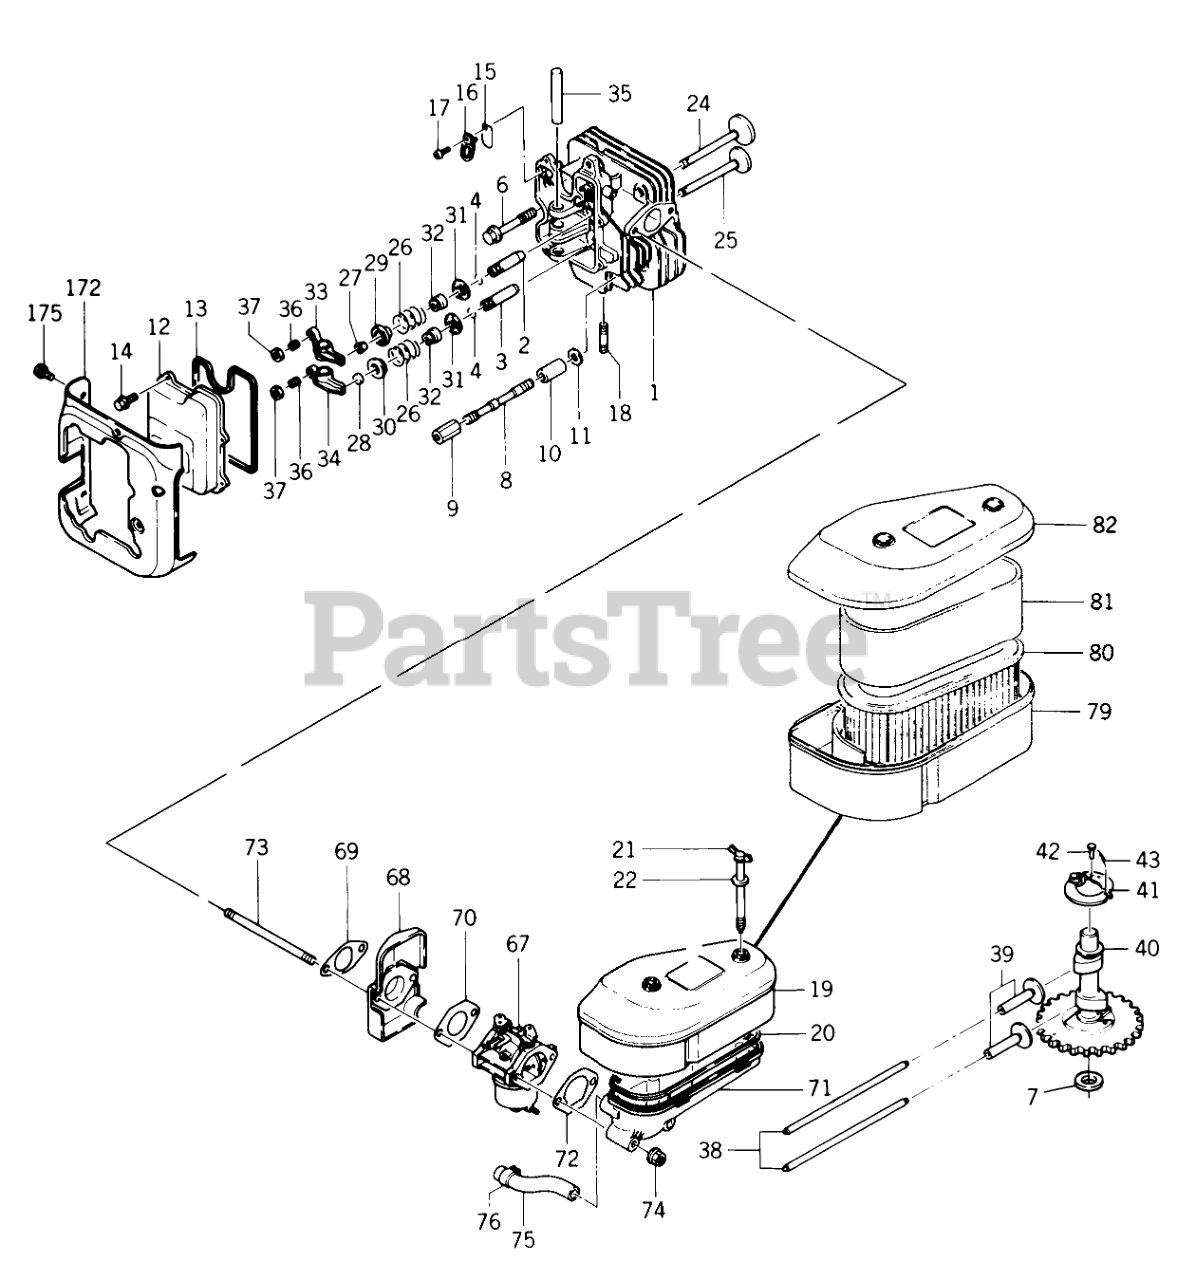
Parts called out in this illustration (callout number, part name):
1	CYLINDER HEAD
2	GUIDE-VALVE(IN)
3	GUIDE-VALVE (EX)
4	RING-SNAP
6	BOLT-HEAD
7	SHIM 1.54
7	SHIM-1.575
7	SHIM-1.61
7	SHIM-1.645
7	SHIM 1.68
7	SHIM-1.715
7	SHIM-1.75
7	SHIM-1.785
7	SHIM-1.82
7	SHIM-1.855
7	SHIM-1.89
10	COLLAR
11	WASHER
12	CASE ROCKER
13	GASKET ROCKER CASE
14	Bolt
15	VALVE
16	PLATE
17	SCREW
19	Air Filter Assembly
20	GASKET AIR FILTER
22	WASHER
24	VALVE INTAKE
25	VALVE EXHAUST
26	Valve Spring
27	COLLET VALVE
28	CAP VALVE
29	RETAINER SPRING
30	RETAINER SPRING
31	SEAT SPRING
32	SEAL-OIL
33	ARM ROCKER
34	ARM ROCKER
35	SHAFT ROCKER
36	SCREW
38	ROD PUSH
39	TAPPET
40	SHAFT-CAM
41	DECOMPRESSOR
43	SPRING
67	Carburetor Assembly See Section 10-5 for complete breakdown
68	INSULATOR
69	GASKET
70	GASKET
71	PIPE INTAKE
72	Gasket
74	NUT
80	ELEMENT AIR FILTER
81	WRAPPER AIR FILTER
82	CAP AIR FILTER
172	SHROUD
175	Bolt 6 x 12
